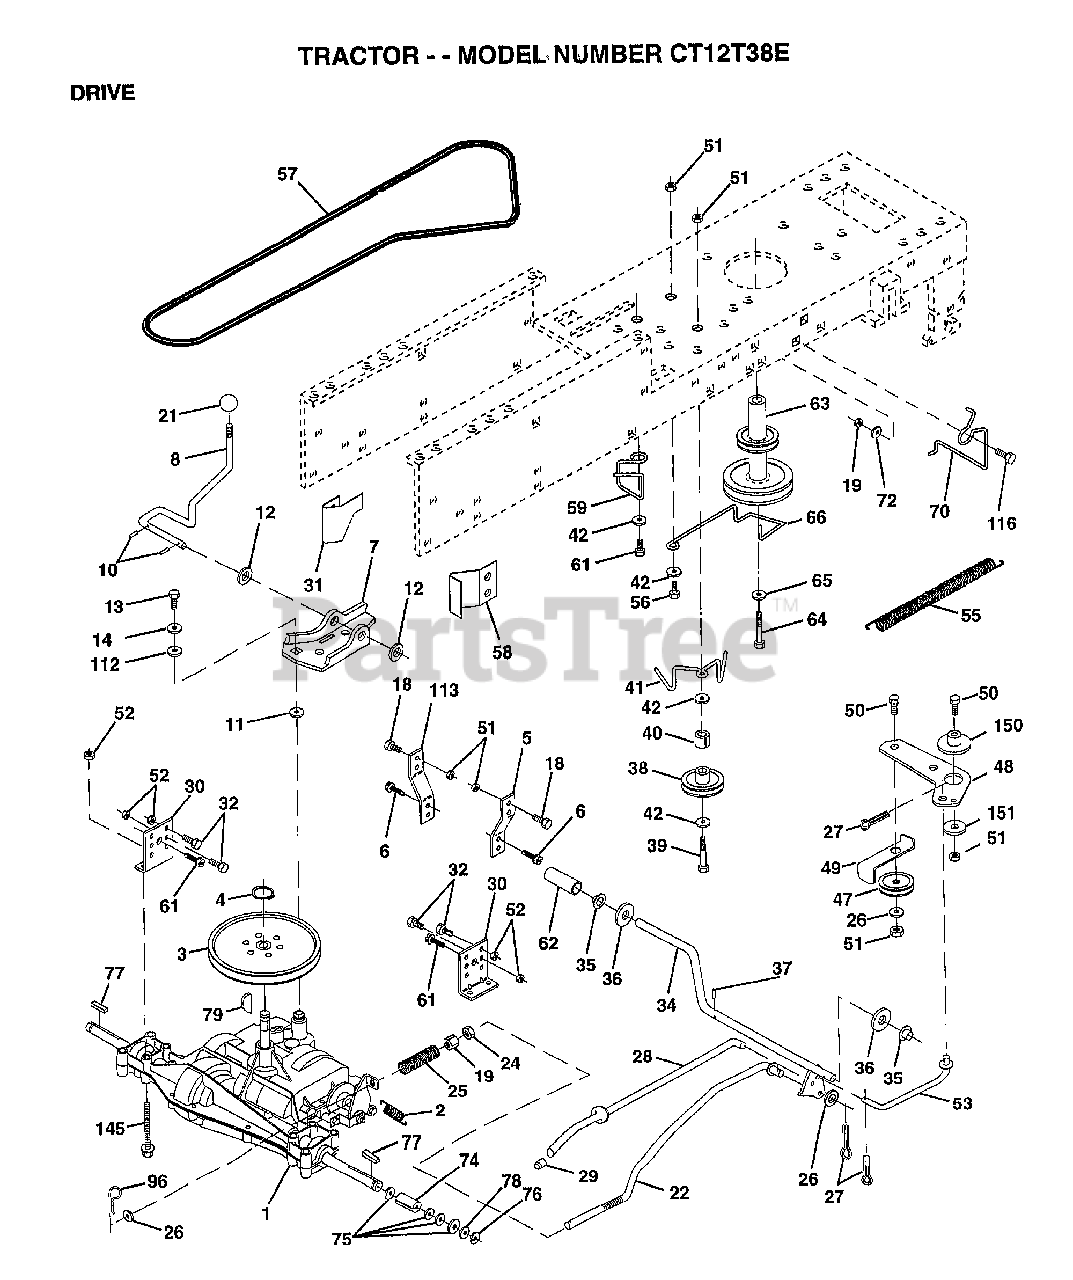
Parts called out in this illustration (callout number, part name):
2	SPRING.BRAKE.RETU
3	PULLEY TRANS
5	STRAP TORQUE
6	SCREW
7	BRKT.SADDLE.SHIFT
8	SHIFT ROD
10	PIN COTTER 1/8
11	WASH-SHFT PLT LT
12	WASHER
13	BOLT.1/4-28.W/PAT
14	LOCKWASHER
18	BOLT
19	NUT
21	KNOB T (1/2-HOLE)
22	BRAKE ROD
24	NUT
25	SPRING ROD LT
26	WASHER
27	COTTER PIN
28	ROD.BRAKE.PARK.LT
29	PLUNGER CAP T
30	TRANSAXLE MTG BKT
31	"KEEPER,BELT LH T"
32	BOLT
34	SHAFT ASM-PEDAL F
35	NYLON BEARING
36	WASHER LT
38	FLAT IDLER PULLEY
39	BOLT
40	SPACER T
41	"KEEPER,BELT.IDLER FLAT"
42	WASHER
48	BELLCRANK.CLUTCH
49	RETAIN BELT
53	"LINK, CLUTCH T"
55	"SPRING, RETURN LT"
58	"KEEPER,BELT RH T"
59	KEEPER BELT CNTSP
61	SCREW
62	PEDAL COVER T
63	PULLEY.ENGINE
64	BOLT
65	LOCKWASHER
66	KEEPER-BELT
70	KEEPER BELT ENG
72	WASHER
74	SPACER AXLE
75	WASHER
76	E-RING LT
77	SQUARE KEY
78	WASHER
96	RETAINER M
112	WASHER LT
113	"STRAP,TORQUE"
116	BOLT RDHD 3/8-16
145	BOLT.HEX.FLGHD
150	BUSHING.BELLCRANK.GRD.DR
151	WASHER
